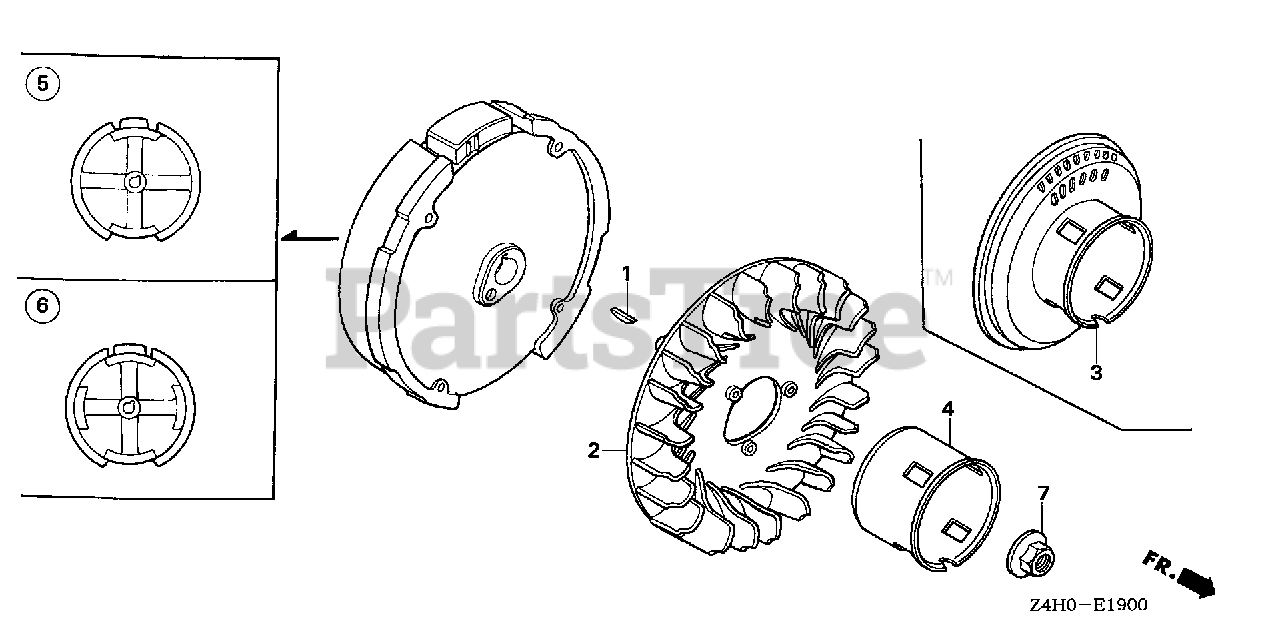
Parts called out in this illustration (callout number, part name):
1	KEY, SPECIAL WOODRUFF (25X18)
2	FAN, COOLING
4	PULLEY, STARTER
7	NUT, SPECIAL (14MM)
